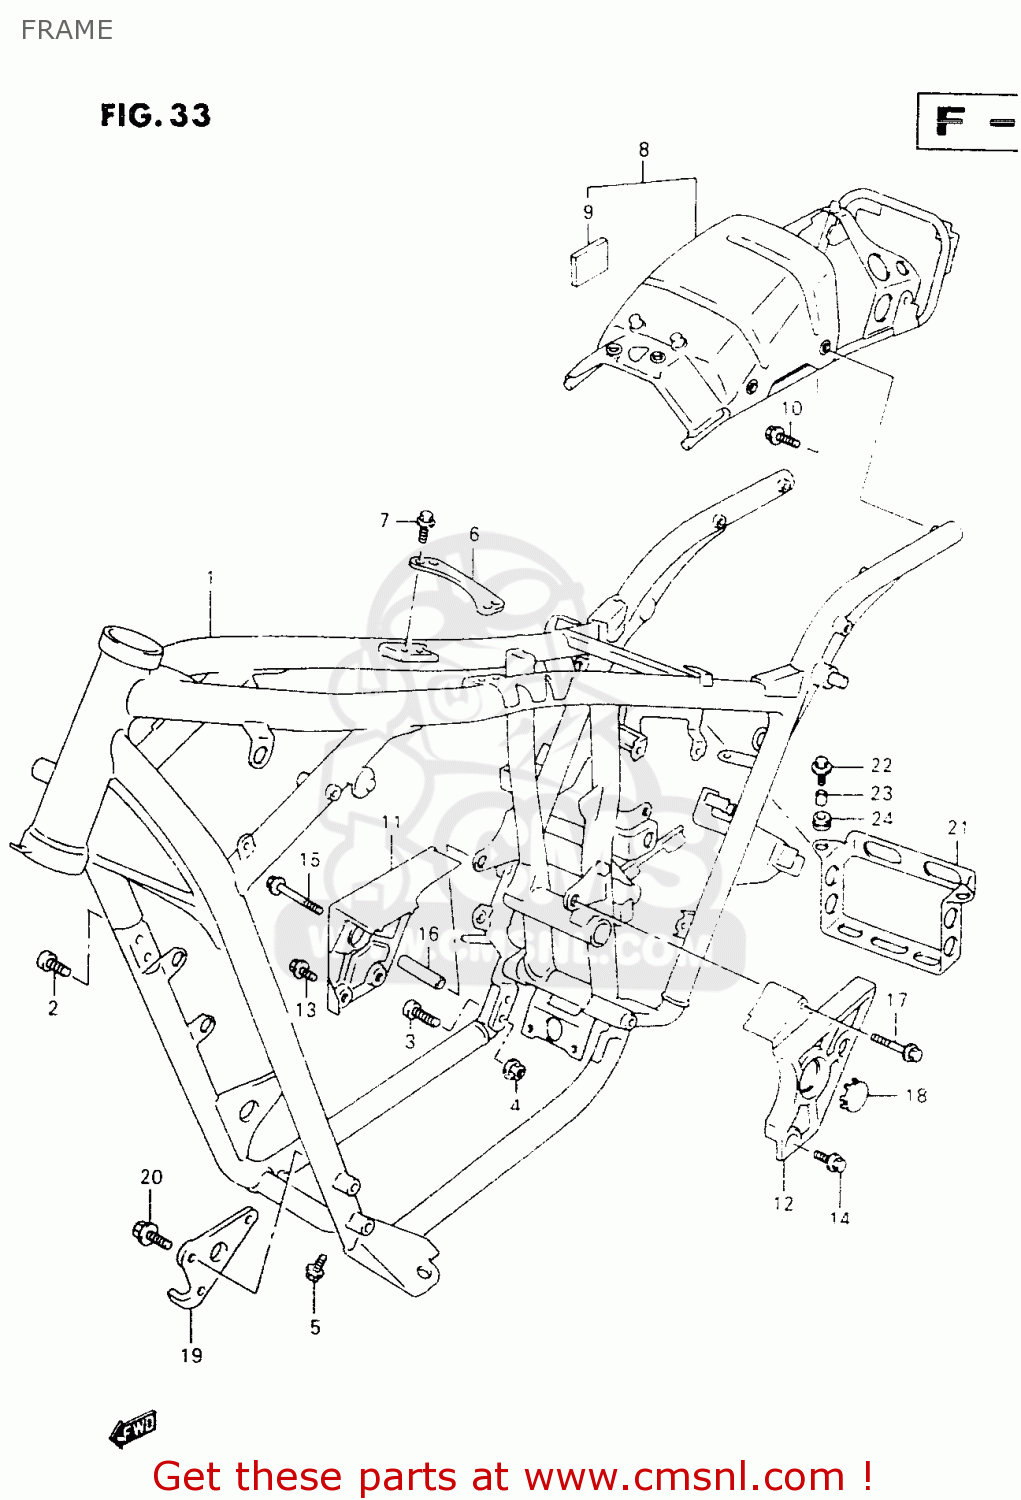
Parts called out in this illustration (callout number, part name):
1	FRAME(BLACK)
2	BOLT
3	BOLT
4	NUT
5	BOLT
6	PLATE,FRAME BODY
7	BOLT
8	BRACE ASSY,RR FRAME
9	PAD
10	BOLT
11	COVER,PIVOT,R
12	COVER,PIVOT,L
14	BOLT,PIVOT COVER
15	BOLT,PIVOT COVER FR,R
16	SPACER,PIVOT COVER,R
17	BOLT,PIVOT COVER UPR,L
18	CAP,RR SWINGING ARM PIVOT,R
19	PLATE,ENGINE MOUNT NO.1,L
20	BOLT
21	HOLDER,BATTERY
22	BOLT(6X16)
23	SPACER(6.5X9X8)
24	CUSHION
